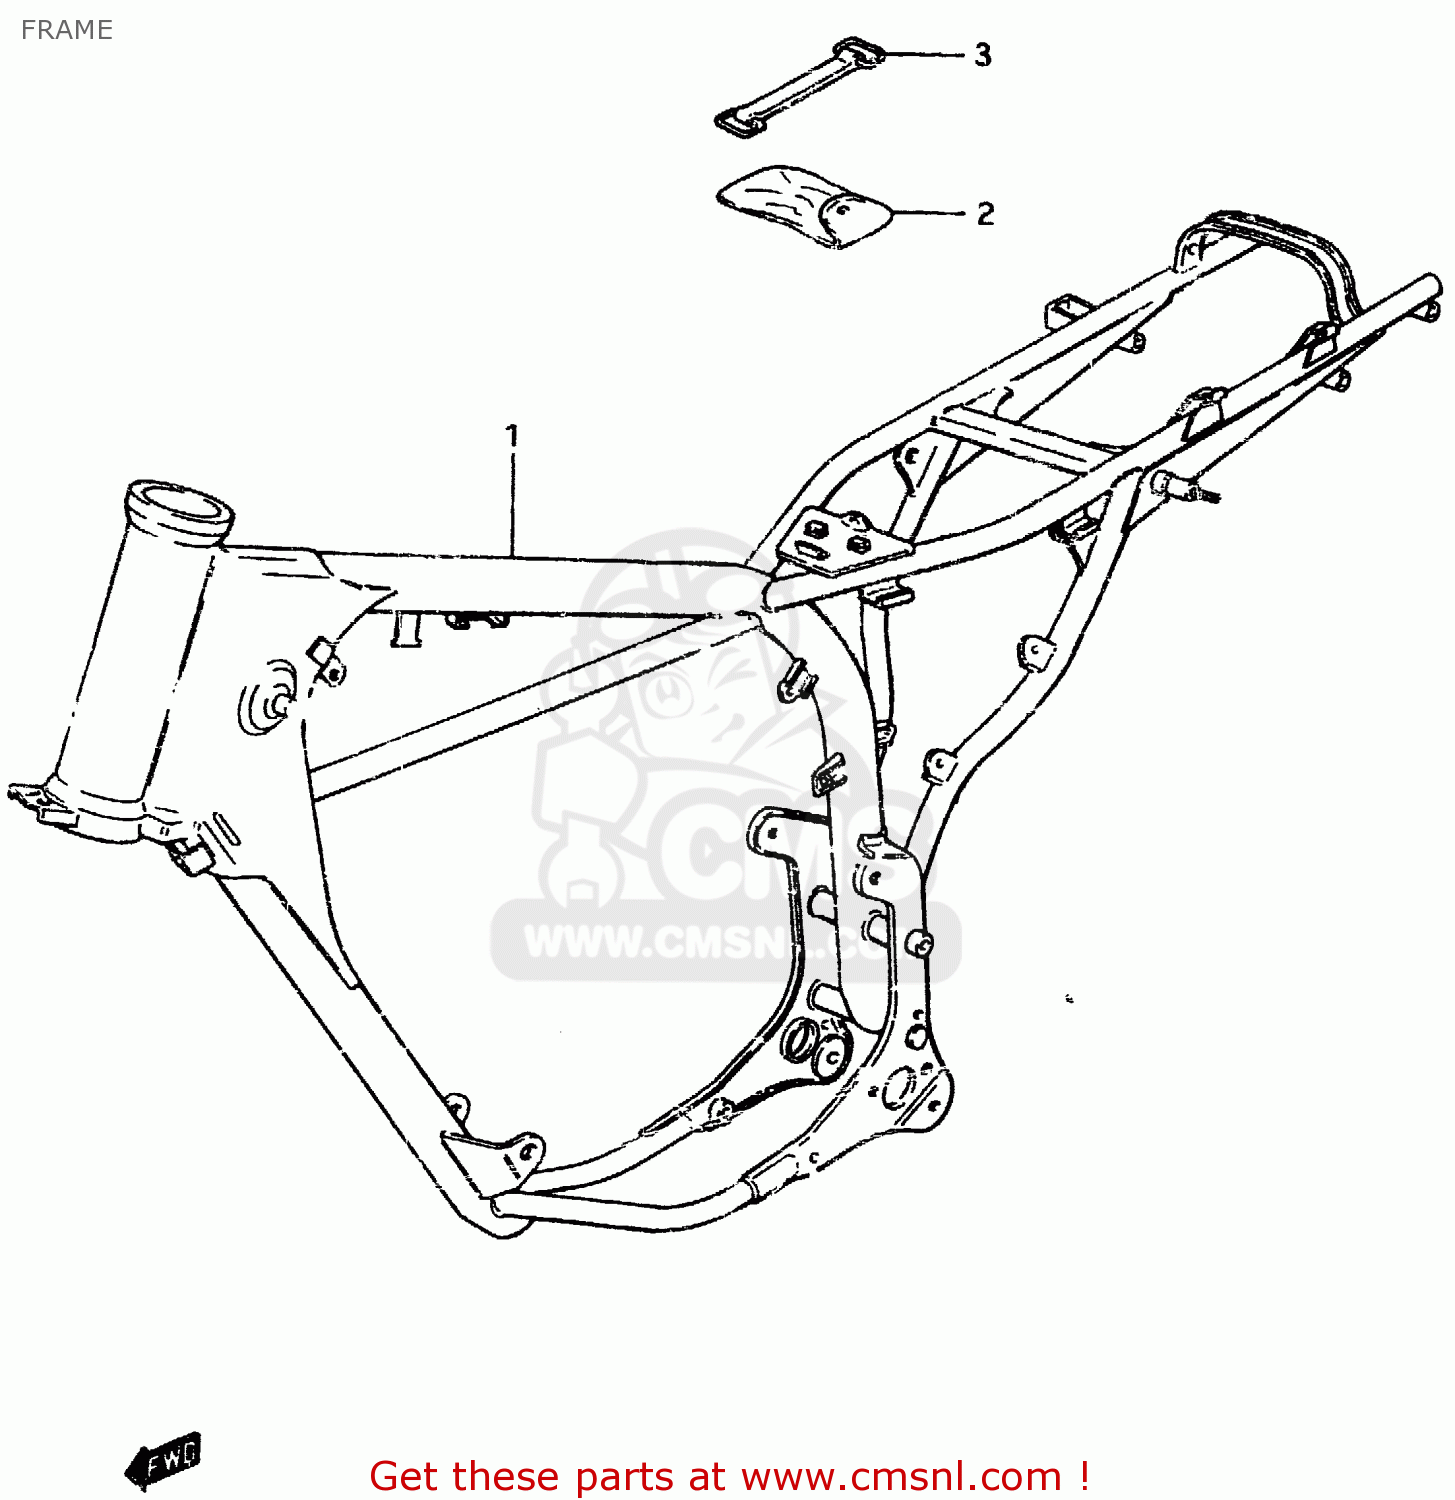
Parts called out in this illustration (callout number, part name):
1	FRAME (BLACK)
2	TOOL SET
3	BAND
